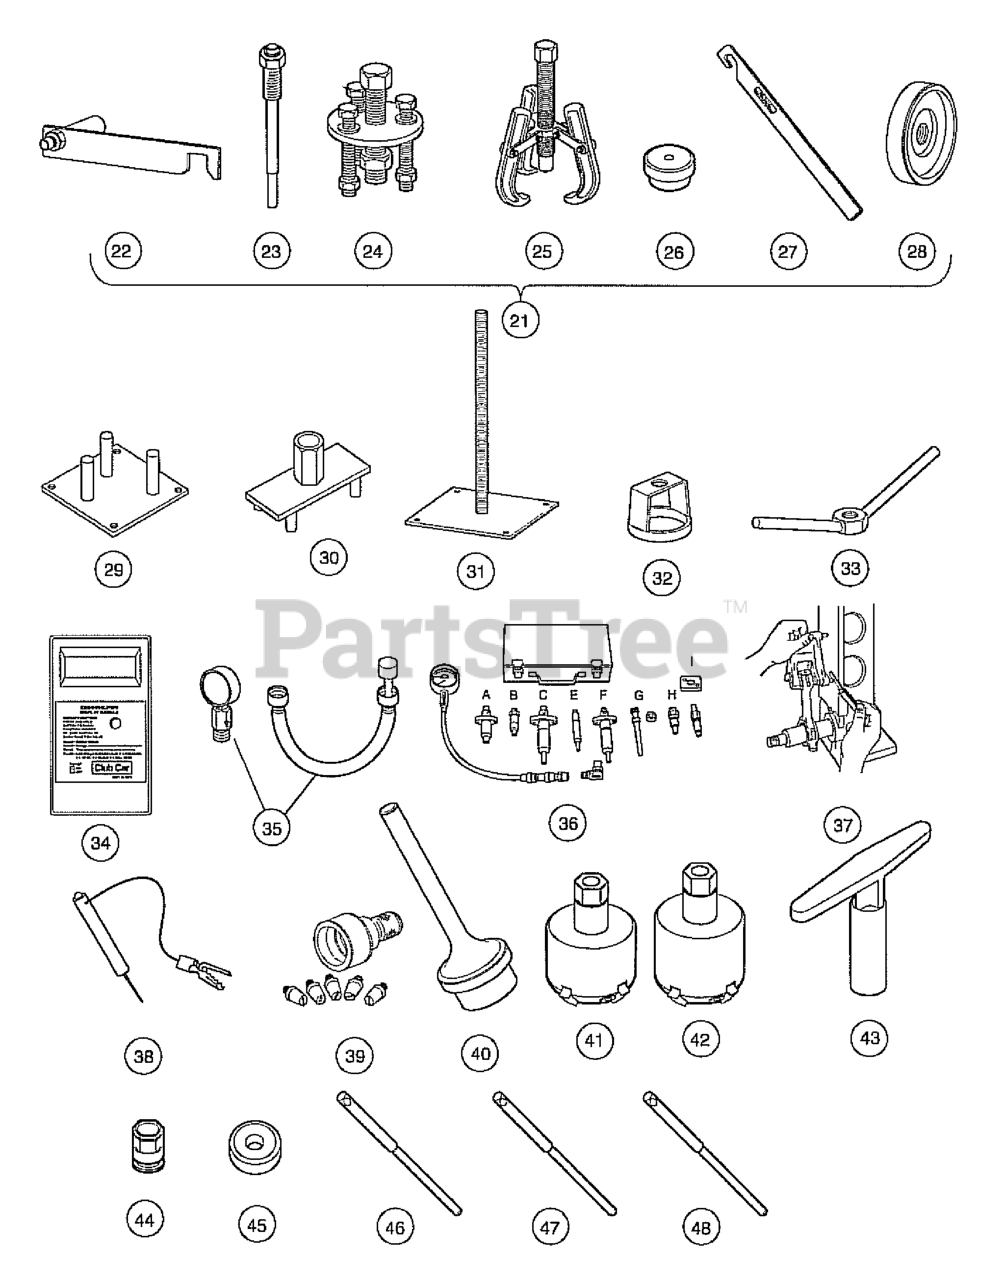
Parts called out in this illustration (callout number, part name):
21	C.C. CLUTCH TOOL KIT
22	Clutch Alignment Tool
23	TOOL, CLUTCH PULLER
24	CLUTCH DRIVE HUB PULLER
25	DRIVEN CLUTCH CAM PULLER
26	DRIVEN CLUTCH PULLER PLUG
27	DRIVE CLUTCH HOLDER TOOL ASM.
28	PRESS WELDMENT
29	TOOL-STATIONARY PRIMARY
30	TOOL-SPIDER PRIMARY
31	TOOL-SPRING COMPRESSION BASE
32	TOOL-SPRING COMPRESSION COLAR
33	TOOL-SPRING COMPRESSION COLAR
34	Communication Display Module
35	COMPRESSION GUAGE AND ADAPTER
36	Compression Tester
37	Connecting Rod Alignment Tool
38	CONTINUITY TESTER
39	Crank Sleeve Setter
40	Crankshaft Bearing Replacement Tool
41	Cutter, Valve Seat, #122
42	Cutter, Valve Seat #115
43	Wrench, T, #505
44	Adapter, T-Wrench
45	Cutter, Valve Seat, 60 Degree (requires item 59)
46	Pilot, 6.6 MM
47	Pilot, 6.62 MM
48	Pilot, 6.65 MM
